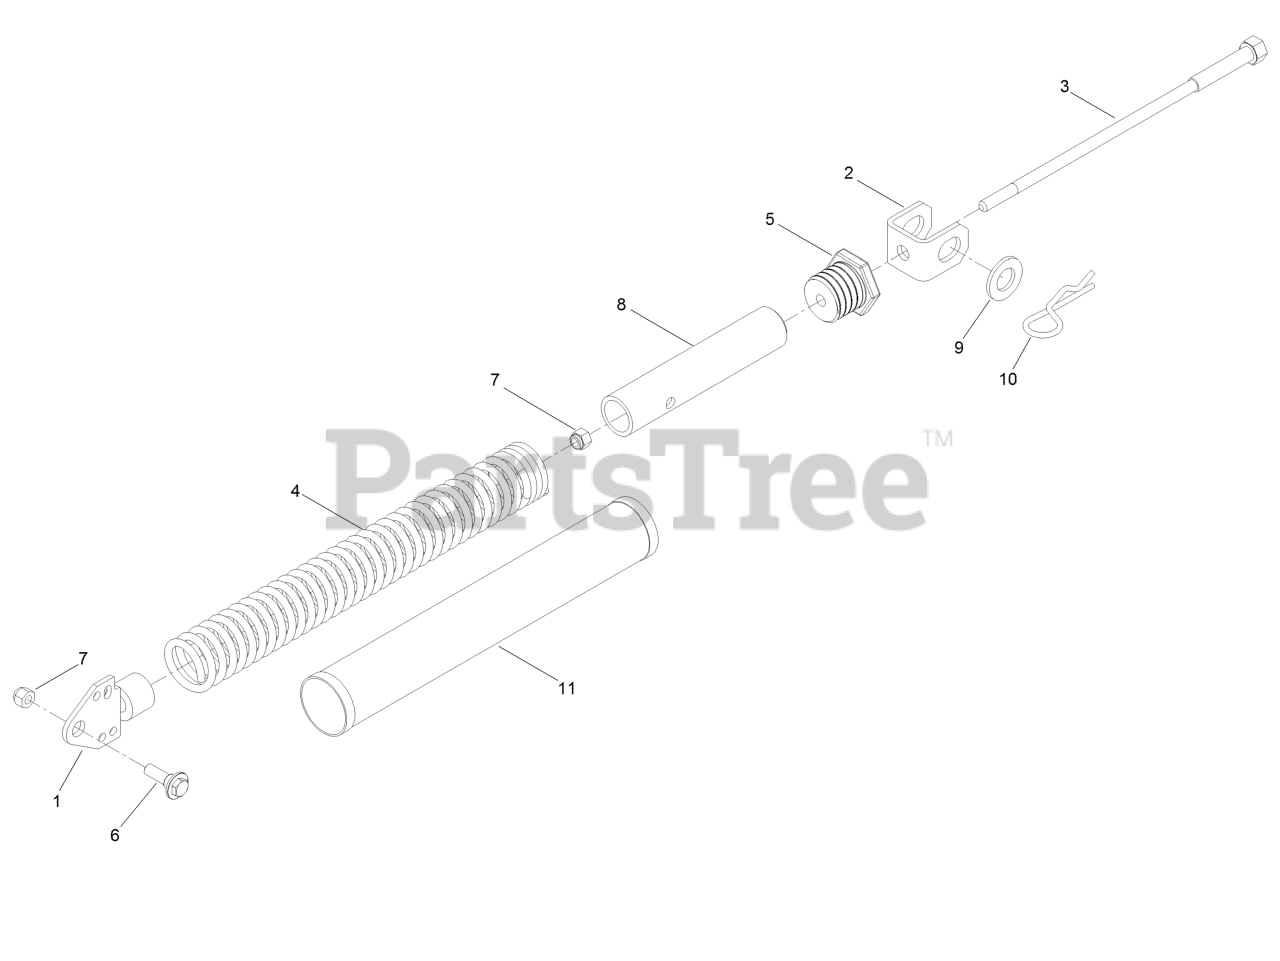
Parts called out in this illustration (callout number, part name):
1	Tensioner-Spring
2	Mount-Lift Assist, Deck
3	Shaft-Adjustment, Spring
4	Spring-Extension
5	Plug-Adjuster, Spring
6	Screw-Shoulder,HWH
7	Nut-Lock, NI
8	Spring-Tube
9	Washer-Flat
10	Pin-Cut Height
11	Cover-Spring, Deck
